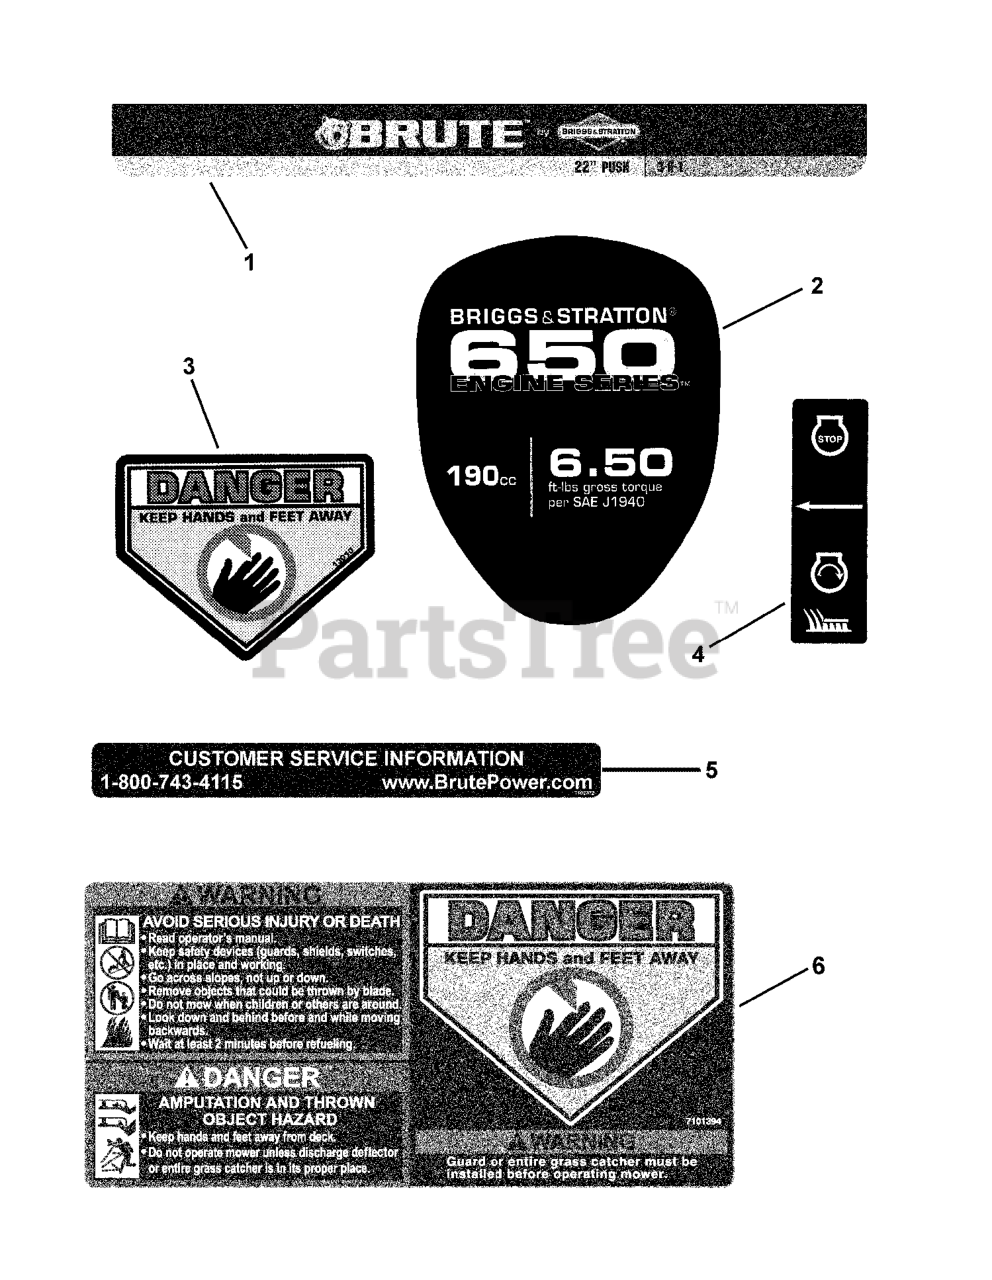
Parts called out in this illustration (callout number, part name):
1	DECAL, Deck Front Brute 22"
2	DECAL, Engine, TP, Brute 650
3	DECAL, Danger, Cut Finger
4	DECAL, OPC Bail, International Symbol
5	DECAL, Customer Service, Brute
6	DECAL, CPSC Warning, Rear Door
